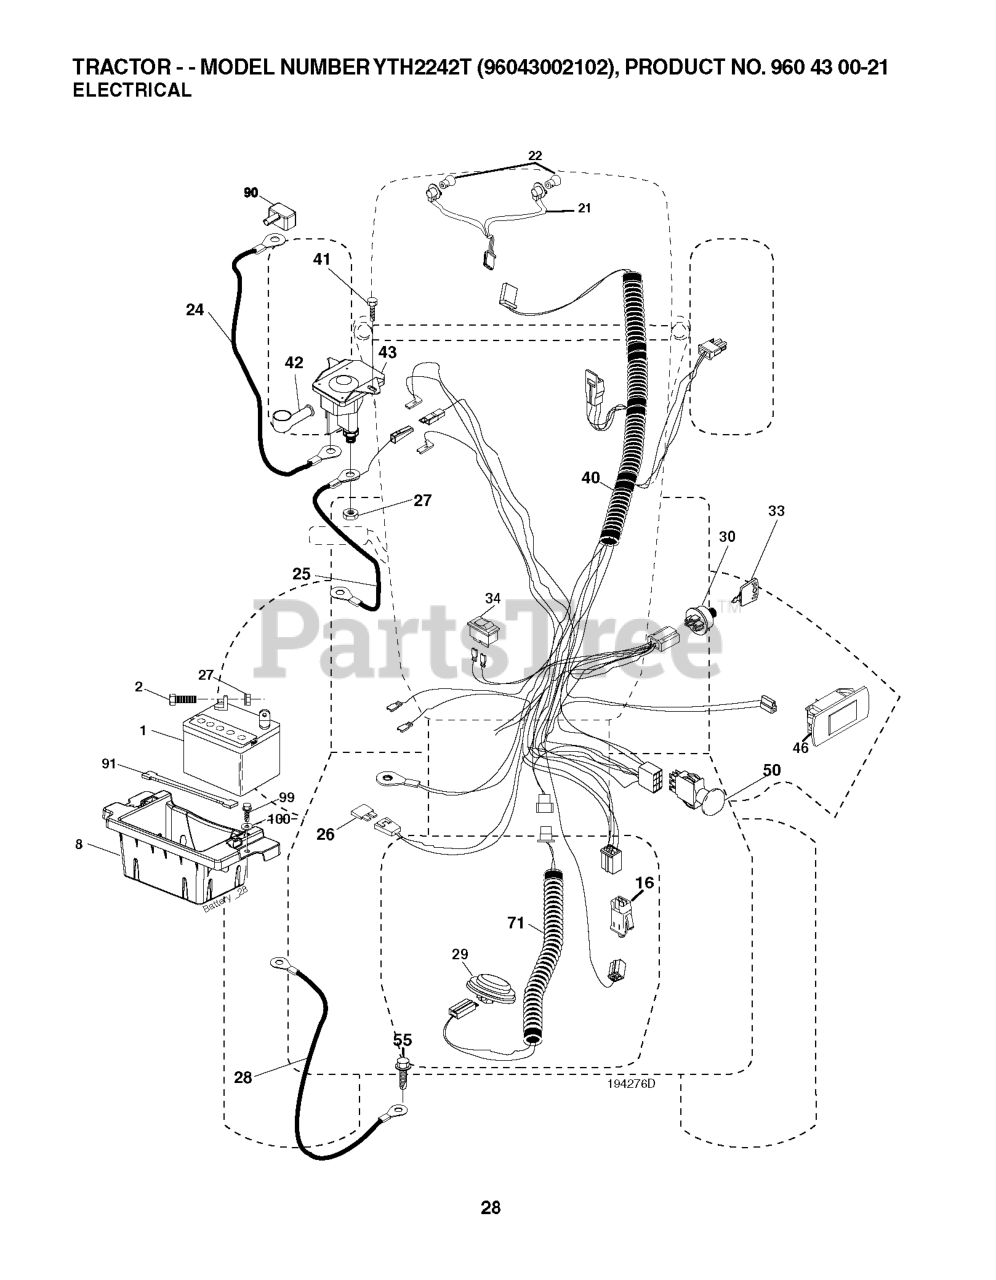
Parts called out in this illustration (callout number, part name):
1	BATTERY 12V .35 AMP
2	BOLT.HEX.1/4.X.3/4.DICHROMATE
8	BOX.BATTERY.MOUNT.FRONT.LT
16	SWITCH INTERLOOK PUSH-IN
21	HARNESS ASSY LIGHT
24	CABLE.BATT.POS.WIRE.TG.DA SOL
25	CABLE.START.RED.17.5".
26	FUSE 20AMP
27	NUT
28	CABLE GROUND 6 GA 21" 90T BLK
29	SWITCH.SEAT.DELTA.OPC.
30	SWITCH.IGN.DELTA.W.LGH.ROS
33	KEY MLD GEN DELTA
40	HARNESS.IGN.DASH.HUQ/P
41	SCREW
42	TERMINAL COVER
43	SOLENOID.W/BRASS.PLUNGER
46	GAUGE.SERVICEMINDER.HR
50	RP.PTO.SWITCH.8 TERMINAL.BLACK
55	SCREW.THDROL.5/16-18X3/4.TTY
71	HARNESS-CHASSIS SUB
90	COVER.TERMINAL.BATTERY
91	STRAP.BATTERY.MOUNT.FRONT(2 2)
99	SCREW HEXWSHR 1/4-20X3/4
100	WASHER
